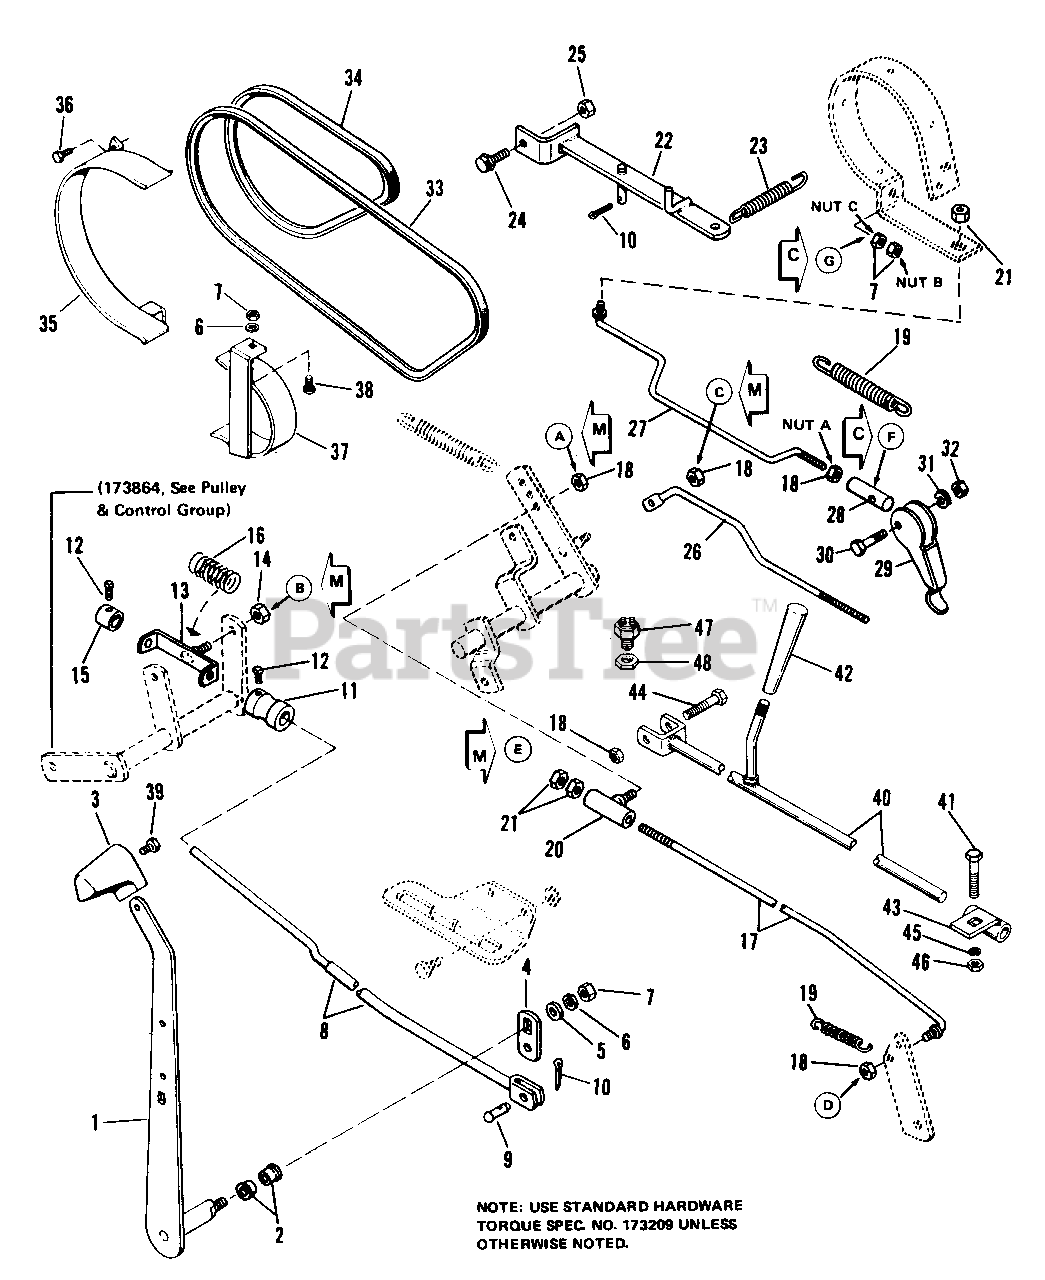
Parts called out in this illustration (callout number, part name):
1	LEVER ASSY
5	WASHER, 3/8
6	LOCKWASHER, 3/8
7	NUT, Hex, full, 3/8-16
10	PIN, Cotter, 3/32 x 3/4
11	DETENT, Brake
12	SETSCREW, 1/4-20 x 3/8
13	GUIDE ASSY, Rod
14	NUT, Hex, Lock, 3/8-24
15	COLLAR, Set
17	ROD ASSY, Brake & Control
18	NUT, Hex, Lock, 5/16-18
20	GUIDE ASSY, Rod
21	NUT, Hex, Full, 5/16-18
22	LEVER ASSY, Brake
24	PAD ASSY, Brake
25	NUT, Hex, Jam, 5/16-18
26	ROD, Brake
27	ROD ASSY, Parking Brake
29	LEVER, Parking Brake
30	CAPSCREW, Hex Hd., 1/4-20 x 1-1/4
31	LOCKWASHER, Dbl., 1/4
32	NUT, Hex, Lock, 1/4-20
33	"V" BELT, Drive
34	"V" BELT, Forward Drive
35	GUARD ASSY, Pulley
36	SCREW, Taptite, 5/16-16 x 5/8
37	GUARD ASSY, Belt
38	BOLT, Carriage, 3/8-16 x 3/4
39	SCREW, Thd. Forming, 1/4-20 x 7/8
40	ROD ASSY, Shift
41	CAPSCREW, Hex Hd., 5/16-18 x 3/4
42	HANDLE, Shift Rod
43	GUIDE ASSY, Shift Assy
44	CAPSCREW, Hex Hd., 5/16-18 x 1-1/2
45	LOCKWASHER, 5/16
46	NUT, Hex, Lock, 5/16-18
47	SWITCH, Interlock
48	NUT, Pal
49	LOCKWASHER, 1/4
50	NUT, Hex, Full, 1/4-20
